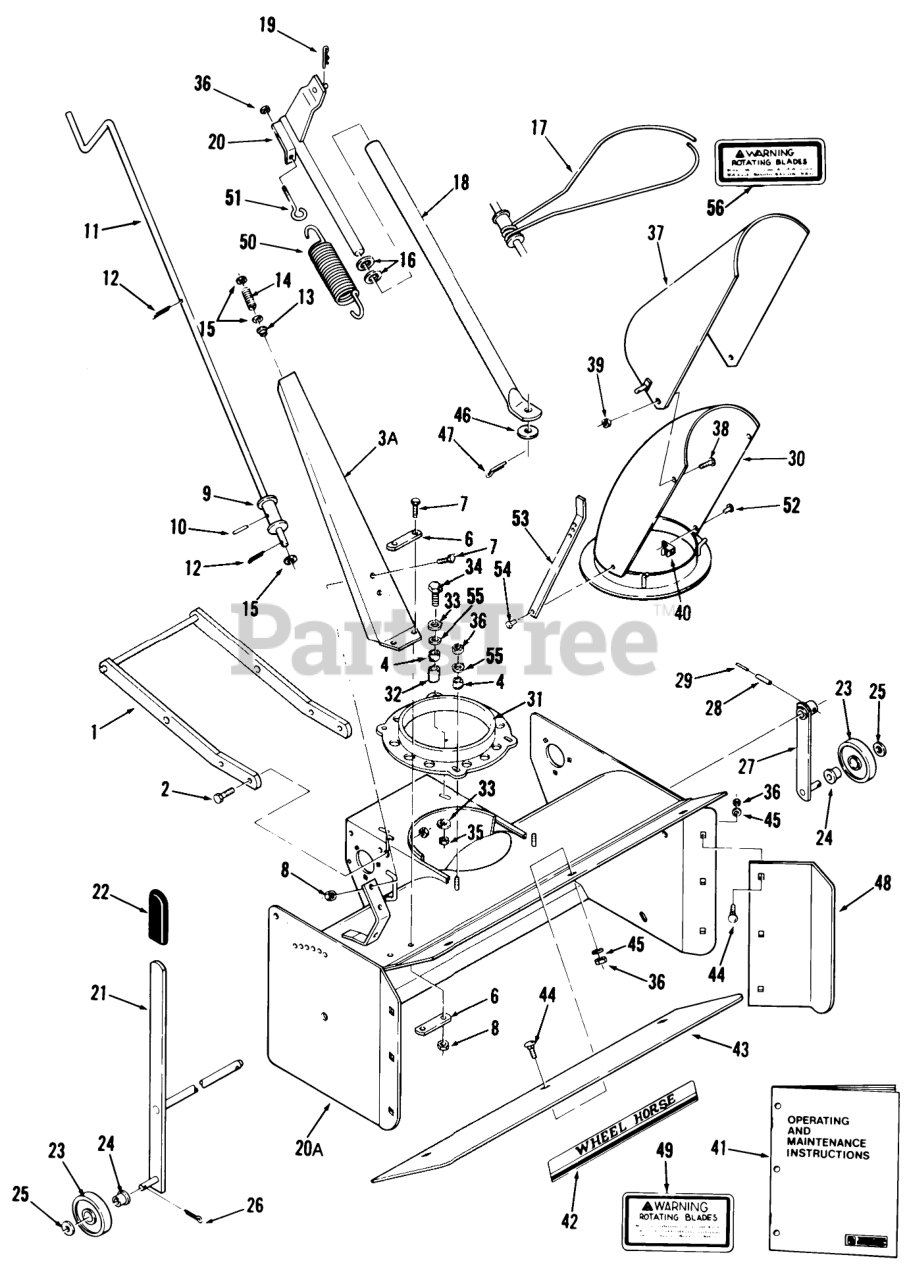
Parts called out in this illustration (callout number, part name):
1	Frame-Mounting
2	Bolt
3	Nut
3A	Crank Support
4	SPACER
6	Bar-Reinforcing
7	Bolt
8	Nut
9	ASSY TUBE CRANK R
10	ROLL PIN 1/4 X 1-1/4
11	CRANK R
12	Pop Rivet
13	NYLINER BUSHING
14	SPRING-COMPRESSION
15	Washer
16	Washer
17	CABLE
18	ASSY LIFT TUBE R
19	Hairpin
20	LIFT ROD ASM
20A	Wrapper Assembly
21	ASSY AUGER SHAFT R
22	GRIP
23	Wheel Assembly (Includes Item 24)
24	Bushing
25	Washer
26	Pop Rivet
27	Wheel Support
28	ROLL PIN 1/4 X 1-1/4
29	PIN-SPIROL
30	S/A SHROUD R
31	COLLAR
32	Spacer
34	Bolt
35	Nut
36	NUT
37	Deflector
38	MACH. SCREW
39	Nut
40	CLAMP
41	Operating and Maintenance Instructions
42	DECAL-REAR
43	Plate
44	Bolt
45	Washer
46	WASHER
47	Cotter Pin
48	Plate
49	DECAL-WARNING
50	SPRING
51	EYEBOLT
52	RIVET-4
53	ARM R
54	RIVET
55	WASHER
56	DECAL-WARNING
